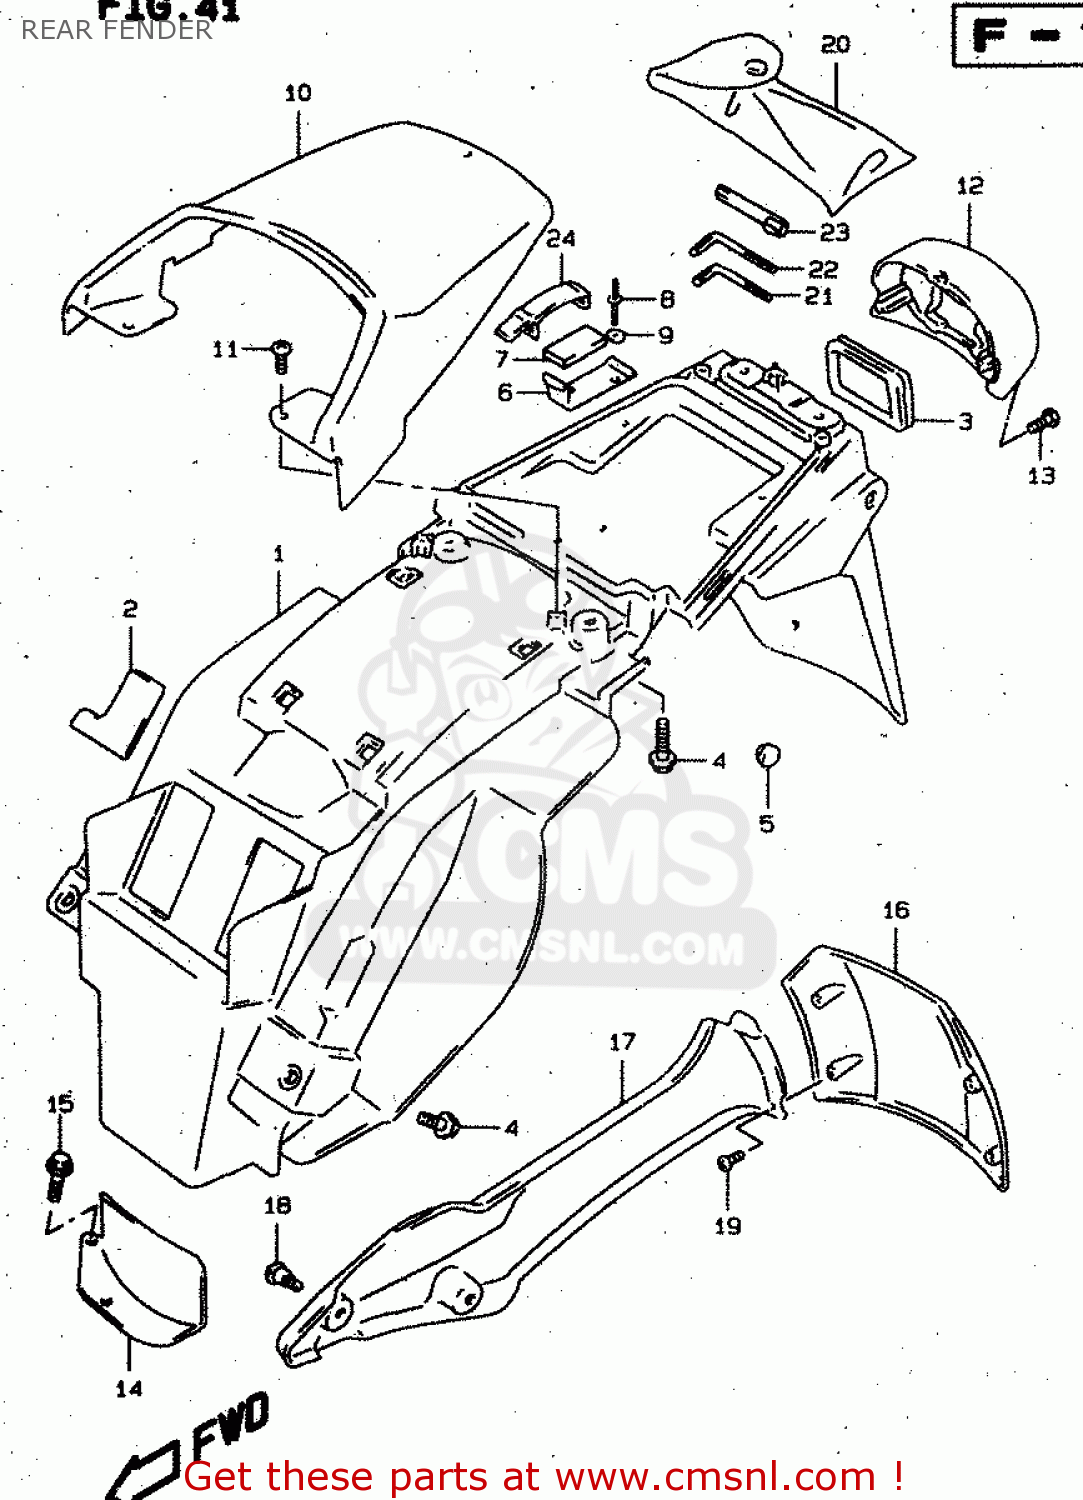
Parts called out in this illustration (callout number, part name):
1	BODY,RR FENDER
2	SHIELD,RR FENDER UPR
3	CAP,RR FENDER EXTENSION
4	BOLT(6X14)
5	PLUG(OD:28)
6	HOLDER,TOOL
7	CUSHION,FRONT FENDER
8	RIVET
9	WASHER
10	COVER,RR FENDER UPR
11	SCREW
12	COVER,RR FENDER RR
13	SCREW
14	MUDGUARD,RR FENDER
15	BOLT,CHAIN CASE
16	FENDER,RR LWR CTR
17	FENDER,RR LWR,R
18	BOLT 6X14
19	SCREW
20	TOOL ASSY
21	SPANNER,HEXAGON(4)
22	SPANNER,HEXAGON(6)
23	SPARK PLUG WRENCH(16)
24	BAND
